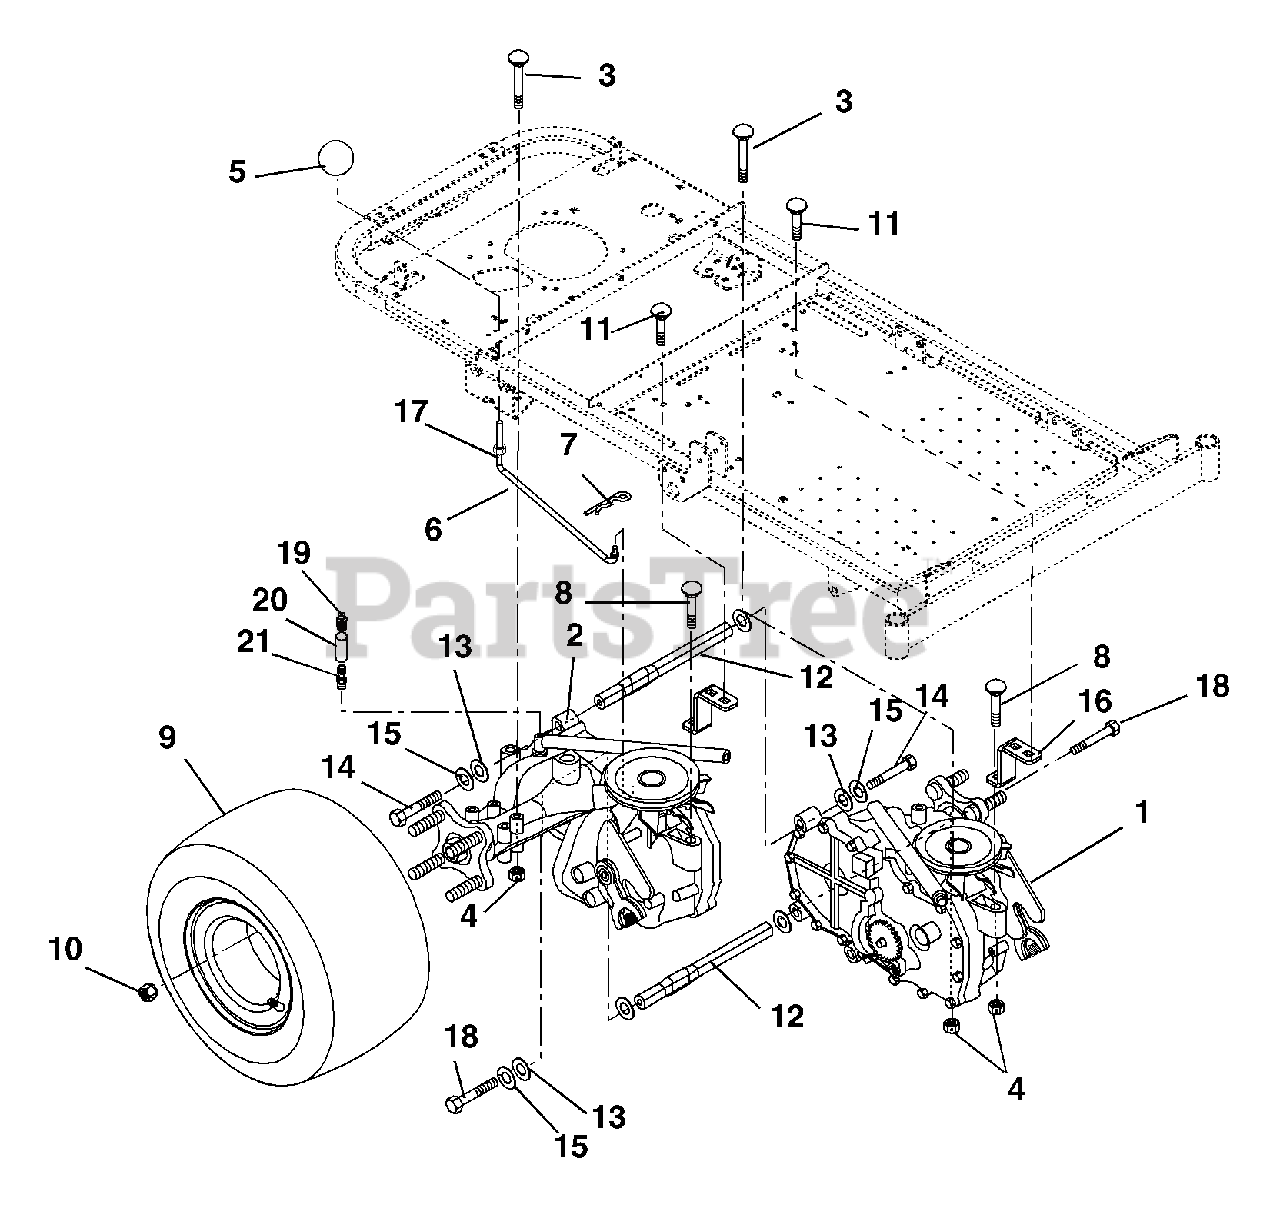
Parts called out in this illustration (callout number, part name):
1	EZT,LH TRANSAXLE-HYDROGEAR
2	EZT,RH TRANSAXLE-HYDROGEAR
3	BLT-RDHDSQSHNK.31-18X2.75G2YWZ
4	@NUT-LK-NYL-FLG .31-18 YWZC
6	ROD, DUMP EZT
7	PIN-HAIR, ENDRIES #25 YWZC
8	@BLT-RDHDSQNK .31-18X2.25 G5YZ
9	ASSY-TIRE 8.5X18 2PLY
10	NUT-LUG .50-20 YWZC
11	@BLT-RDHDSQNK .31-18X1.00 G5YZ
13	@WSHR-FL-STL.344X.688X.065YWZC
14	@BLT-HEX .31-18X2.50 GR5 YWZC
15	@WSHR-LK .31X.078 REG YWZC
16	TORQUE STRAP
17	@NUT-HEX .25-20 YWZC
18	@BLT-HEX .31-18X2.00 GR5 YWZC
19	CAP-VENT .50
20	HOSE - VENT
21	FTG-STR .50 O-RING
